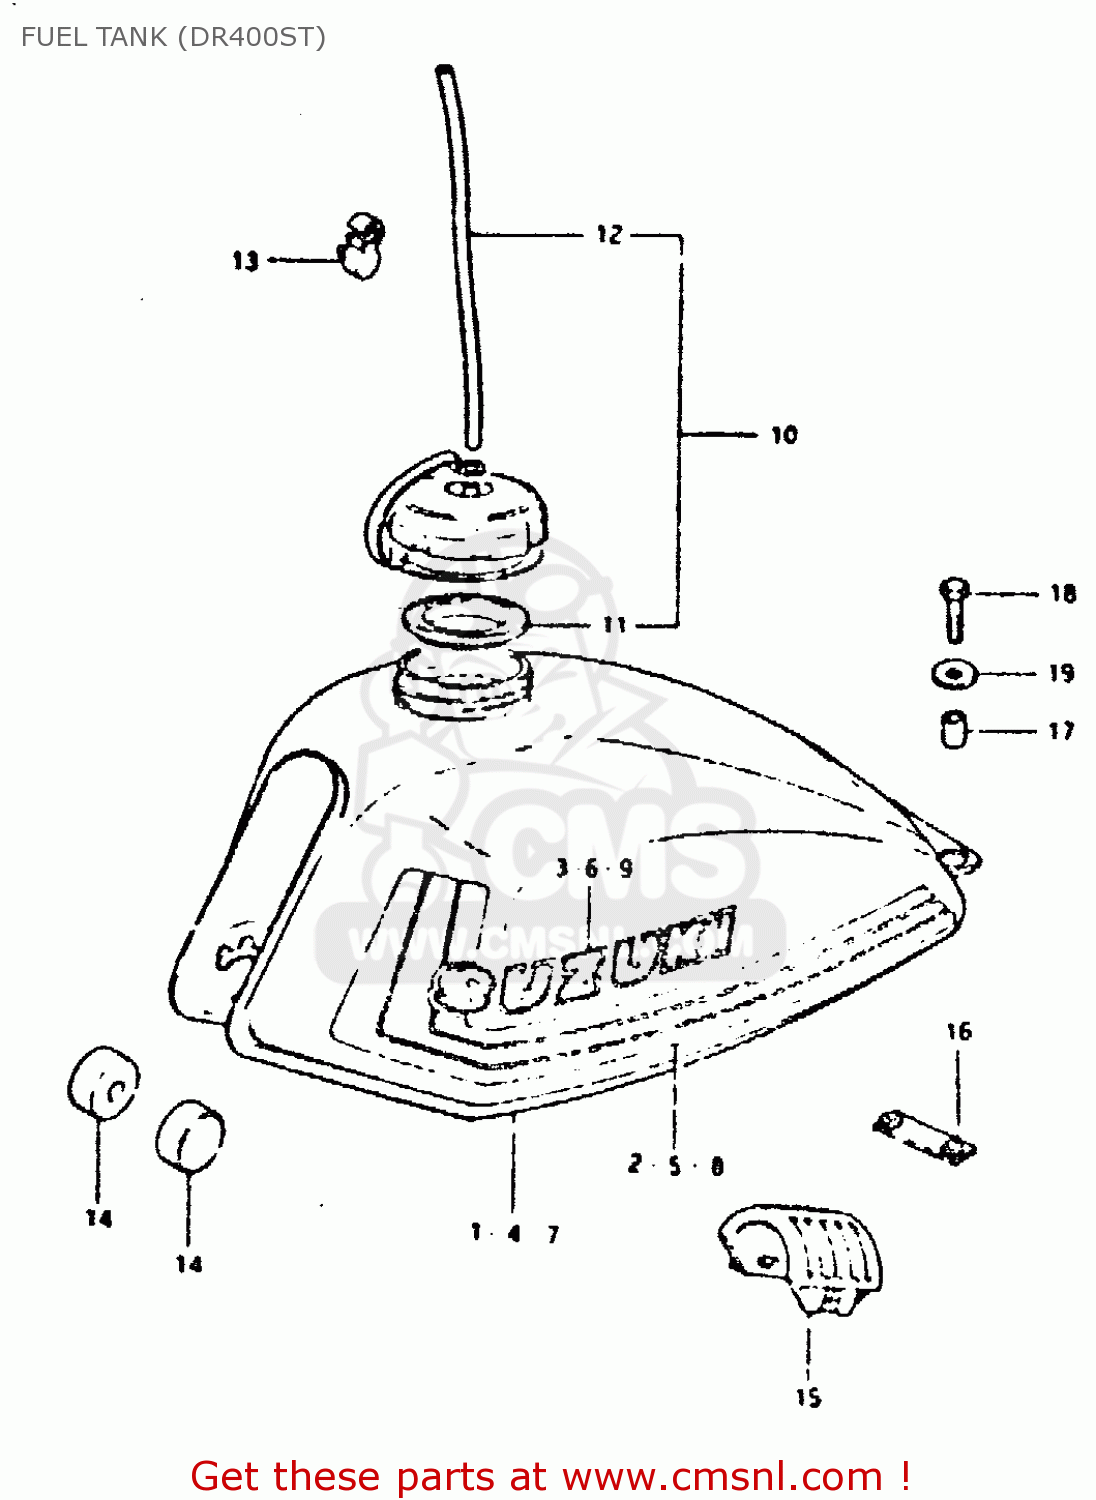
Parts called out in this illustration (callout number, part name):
1	TANK ASSEMBLY,FUEL
2	TAPE SET,FUEL TANK STRIPE
3	EMBLEM,FUEL TANK
4	TANK, FUEL (BLUE)
5	TAPE SET
6	EMBLEM,FUEL TANK
7	TANK, FUEL (YELLOW)
8	TAPE SET,FUEL TANK STRIPE
9	EMBLEM,FUEL TANK
10	CAP SET,FUEL TANK
11	GASKET,FUEL TANK CAP (NAS)
12	HOSE
13	CLAMP,FUEL TANK BREATHER HOSE
14	CUSHION
15	CUSHION,FUEL TANK
16	CUSHION,FUEL TANK,REAR
17	SPACER (6.1X8X12)
18	BOLT
19	WASHER (6.5X24X1.6)
